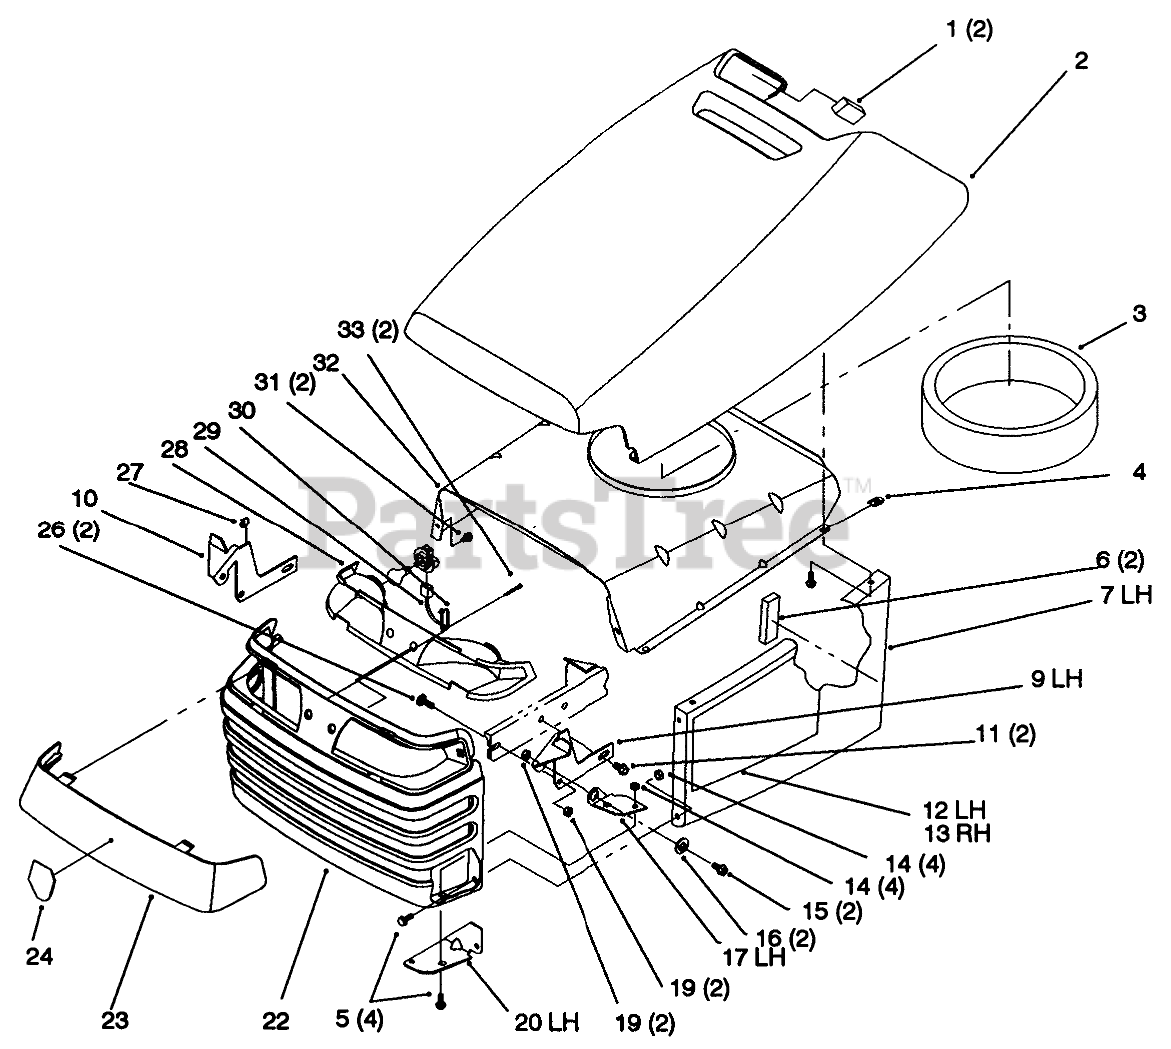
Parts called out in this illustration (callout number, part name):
1	FOAM-HOOD
2	HOOD ASM
3	SEAL-AIR INLET, TWIN
5	SCREW-HWH
6	FOAM-SIDEPANEL
7	HOOD-SIDE, LH
8	HOOD-SIDE, RH
9	Bracket-Hinge LH
10	Bracket-Hinge RH
11	SCREW-HWHTF
12	DECAL - LH HOOD
13	DECAL - RH HOOD
14	NUT-LOCK, HHF
15	SCREW-HH
16	BUSHING
17	Hinge-Hood LH
18	Hinge-Hood RH
19	NUT-LOCK, NI
20	Bracket-Hood Hinge LH
21	Bracket-Hood Hinge RH
22	Screen/Grill ASM
23	LENS - HEADLIGHT
24	EMBLEM-HORSEHEAD
26	BOLT-CARR
27	CLIP-RETAINER, WIRE
28	HEADLIGHT REFLECTOR ASM
29	HARNESS-WIRE, LIGHTS
30	TIE-CABLE
31	SCREW-PLASTITE
32	Baffle-Hood Upper
